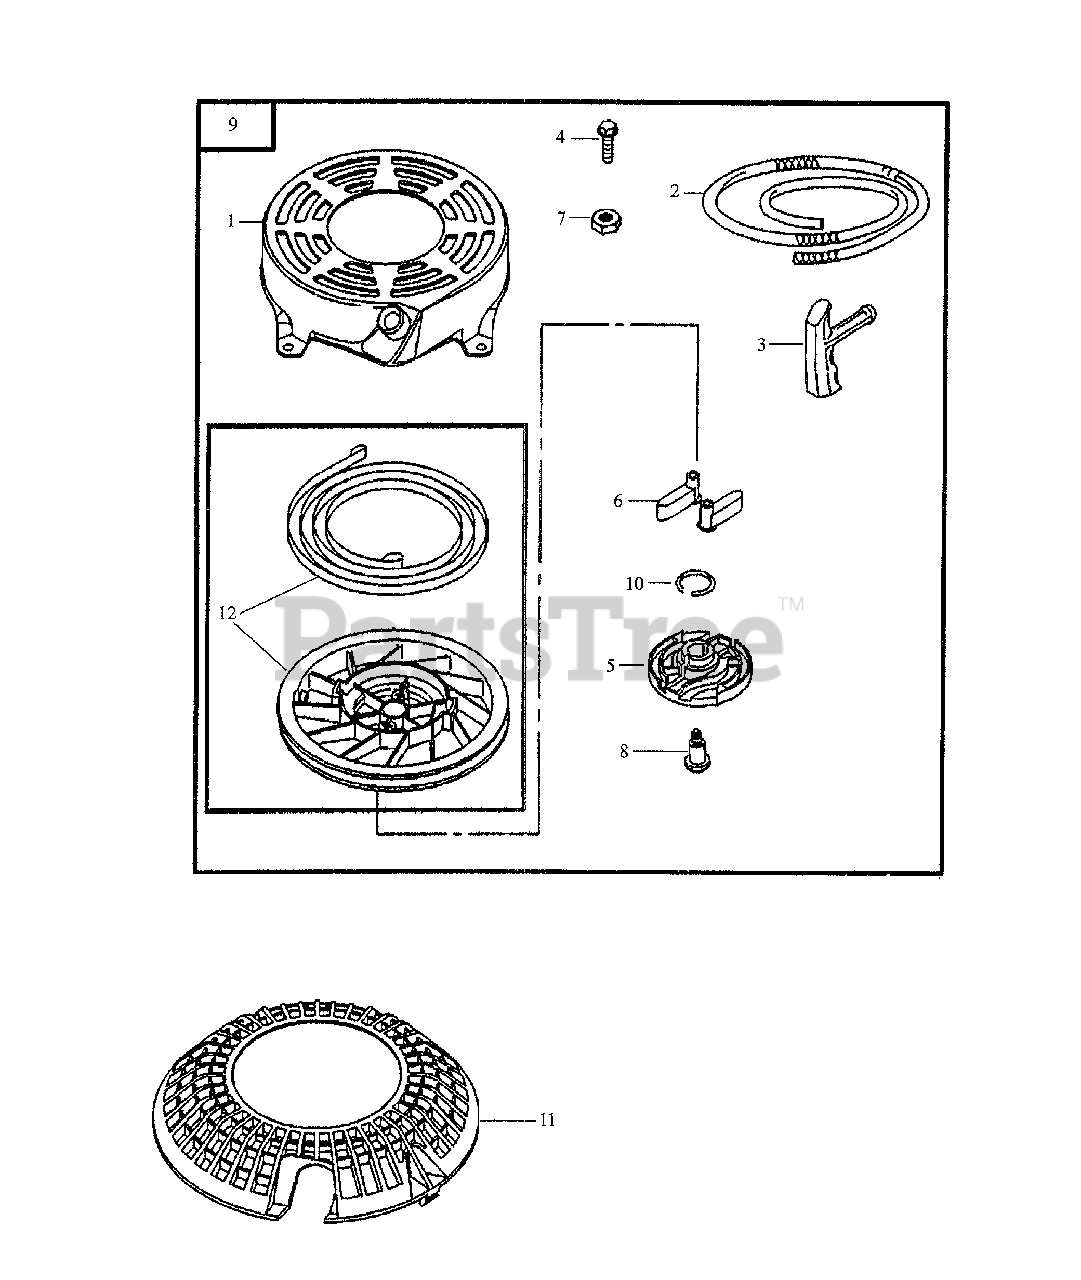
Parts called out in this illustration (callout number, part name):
1	Housing, Rewind
2	Rope
3	Grip, Starter
4	Screw
5	Platem Pawl Friction
6	Pawl, Ratchet
7	Nut
8	Screw
9	Starter, Rewind
10	Spring, Friction
11	Guard, Rewind
